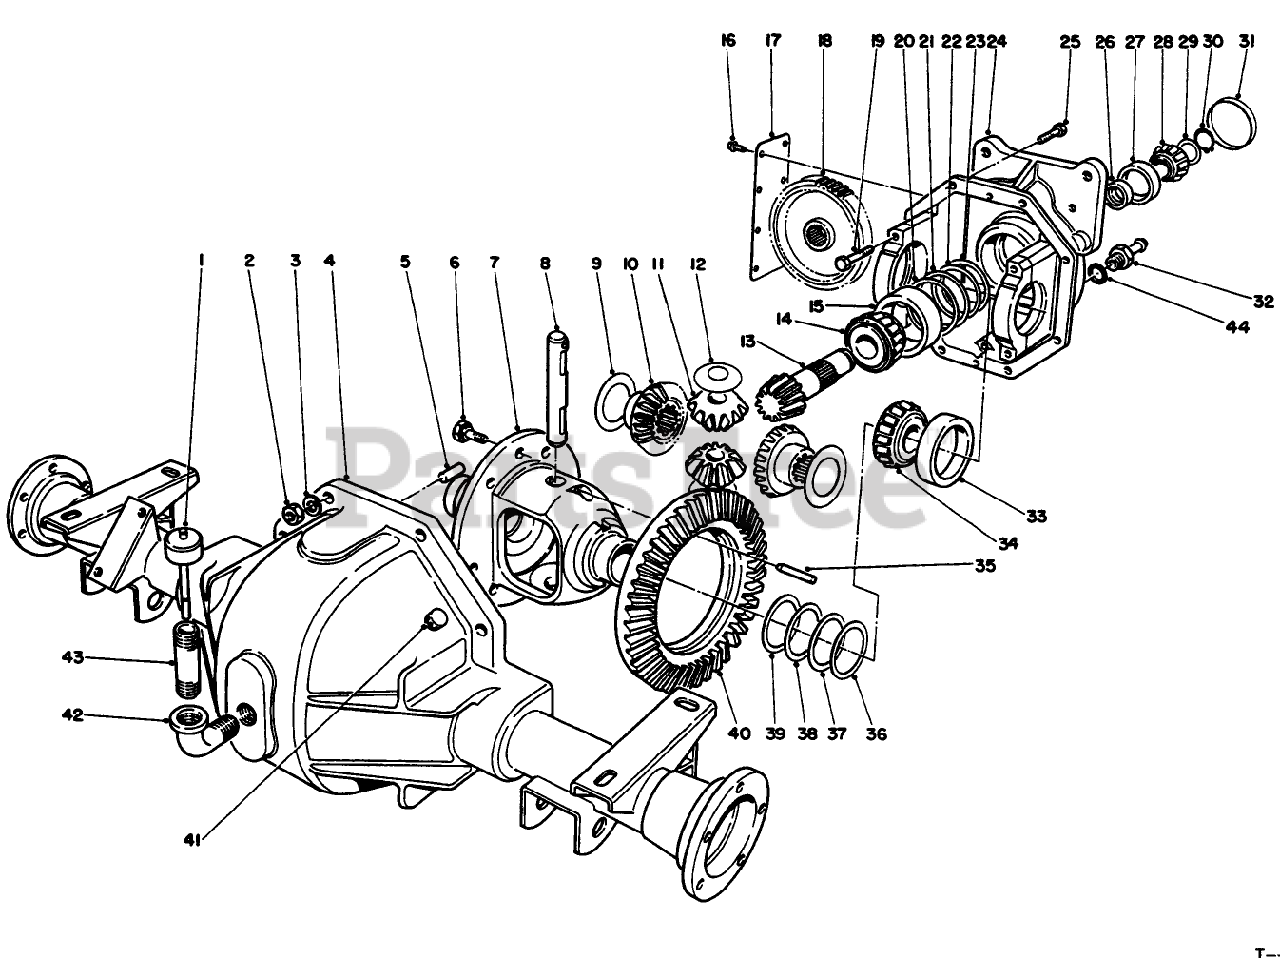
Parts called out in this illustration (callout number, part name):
1	DIPSTICK
2	NUT-HEX
3	WASHER-LOCK
4	HSG TUBE & PAD LWR B
5	PIN-DOWEL
6	SCREW-GEAR, DRIVE
7	CASE-DIFFERENTIAL
8	SHAFT-MATE, PINION
9	WASHER-THRUST
10	GEAR-DIFFERENTIAL
11	PINION-DIFFERENTIAL
12	WASHER-THRUST, PINION
14	BEARING-ROLLER, CONE TAPER
15	BEARING-TAPER, CUP
16	SCREW
17	COVER-GEAR
18	GEAR-INPUT, TRANSMISSION
19	SCREW-HH
20	SHIM-PINION (.003)
21	SHIM-PINION (.005)
22	SHIM-PINION (.010)
23	SHIM-PINION (.030)
24	Upper Housing Assembly (Incl. Ref. #19)
25	SCREW-HH
26	SPACER-BEARING
27	BEARING-CUP
28	CONE-BEARING
29	SHIM-BEARING, FRONT
29	SHIM-FRONT BEARING, .053
29	Shim-Front Pinion .082
30	RING-SNAP
31	PLUG-CUP
32	Fitting-Hose Barb (Incl. Ref. #44)
33	CUP-BEARING, ROLLER
34	BEARING-ROLLER, CONE
35	PIN-ROLL
36	SHIM-BEARING, DIFFERENTIAL (.003)
37	SHIM-BEARING, DIFFERENTIAL (.005)
38	SHIM-BEARING, DIFFERENTIAL (.010)
39	SHIM-BEARING, DIFFERENTIAL (.030)
40	Gear-Ring
42	FITTING-ELBOW-90
43	PIPE NIPPLE
44	O-RING
